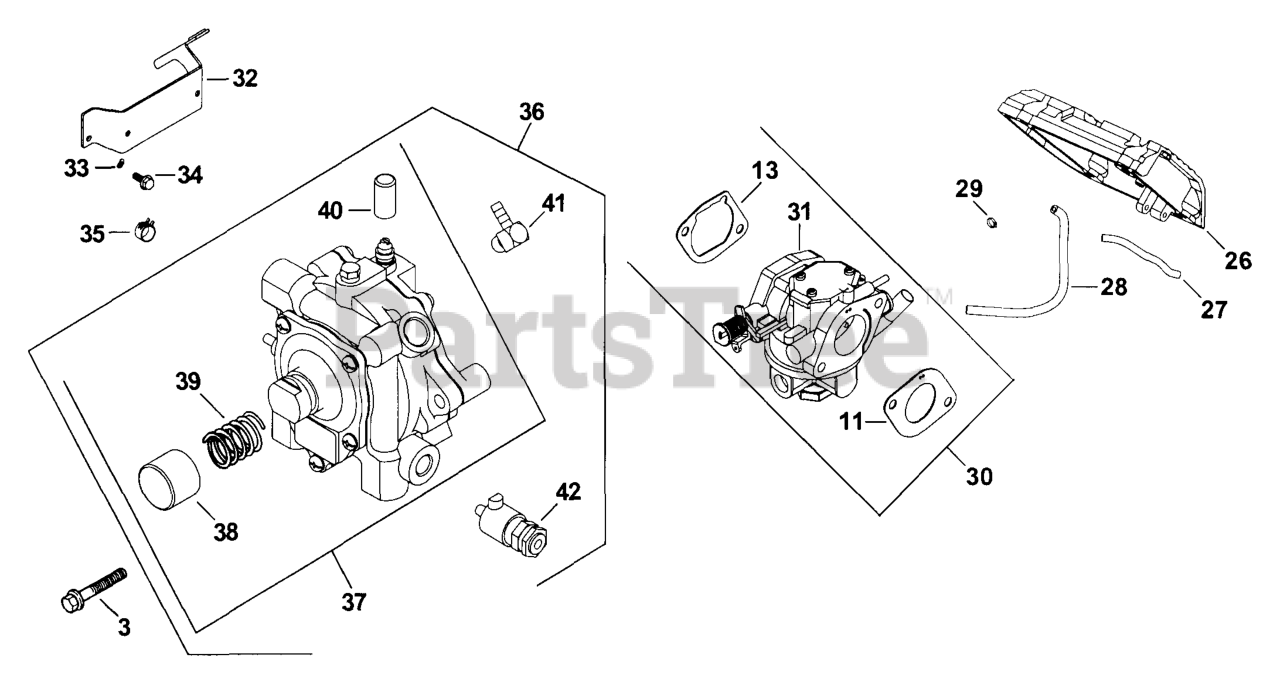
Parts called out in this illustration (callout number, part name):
3	SCREW, FLG M6X1.0X40 - DISCONTINUED
11	GASKET, CARBURETOR
13	GASKET, AIR CLEANER BASE
26	COVER, VALVE NO. 1 - DISCONTINUED
28	LINE, VACUUM - DISCONTINUED
29	CLAMP, HOSE USE 25 237 12-S
30	CARBURETOR W/GASKETS - DISC.
32	BRACKET, LP FUEL - DISCONTINUED
33	WASHER, INT TOOTH LOCK 1/4"
34	SCREW, THD FROM M5X0.8X30-DISCONTINUED
35	CLAMP, HOSE
36	REGULATOR - DISCONTINUED
37	REGULATOR, 2 STAGE FUEL-USE 24 403 23-S
39	SPRING, ANTI-TAMPER
41	FITTING, 90 BARBED
42	SOLENOID, 12VDC LOCKOFF-(#2443510S)
2405004-S	FILTER, DRY FUEL - (#2405026S)
2475720-S	KIT, REPAIR SERVICE GASKET
2851804-S	LEAD - DISCONTINUED
2875708-S	KIT, CHOKE REPR W/GASKETS-(#DSC)
